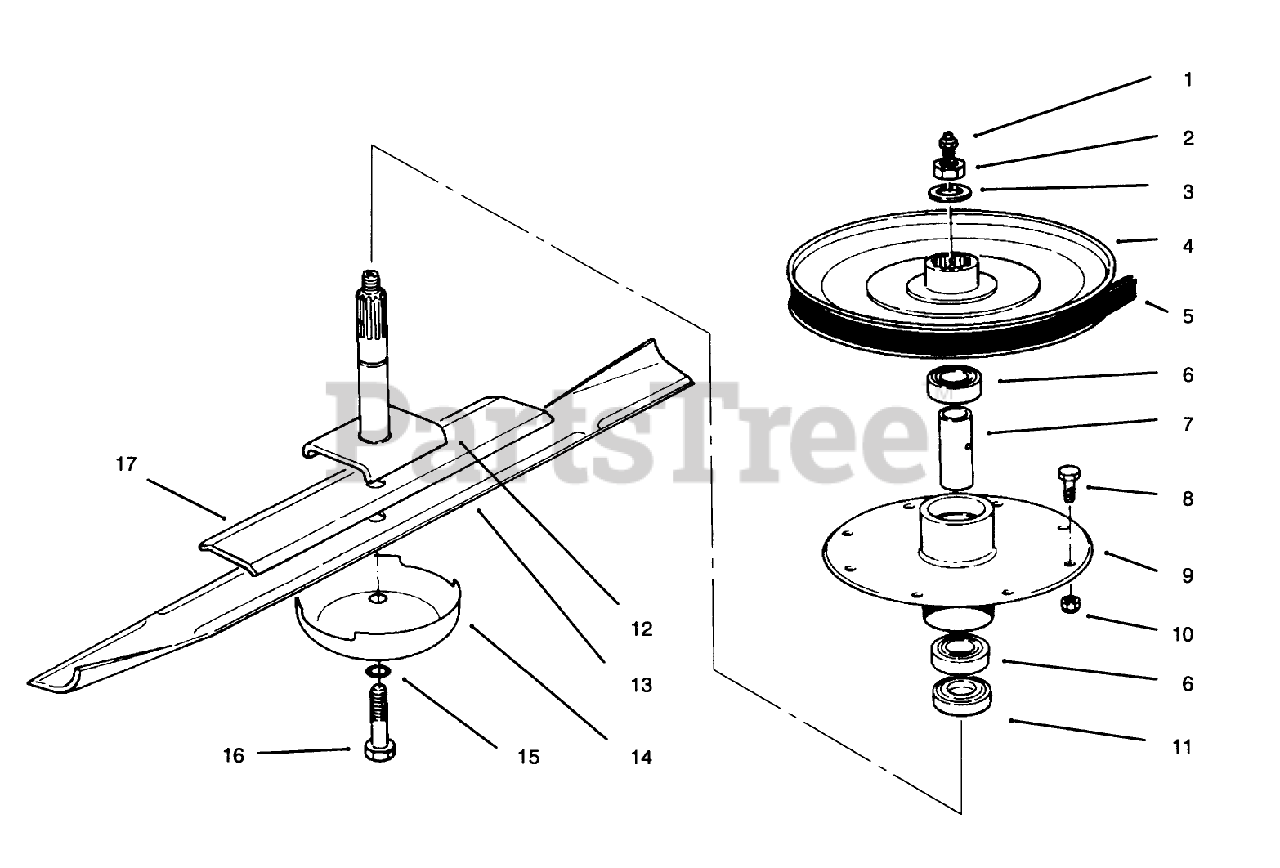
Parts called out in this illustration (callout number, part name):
1	FITTING-GREASE
2	NUT-HEX
3	WASHER
4	PULLEY ASM
5	V-BELT
6	BEARING-BALL
7	SPACER-BEARING
8	SCREW-HH
9	HOUSING-SPINDLE
10	NUT-LOCK, NI
11	SPACER
12	SHAFT-SPINDLE
13	BLADE-RECYCLER
14	CUP-SCALP, ANTI
15	WASHER-LOCK/SP
16	SCREW-BLADE
17	BLADE SPACER ASSEMBLY
